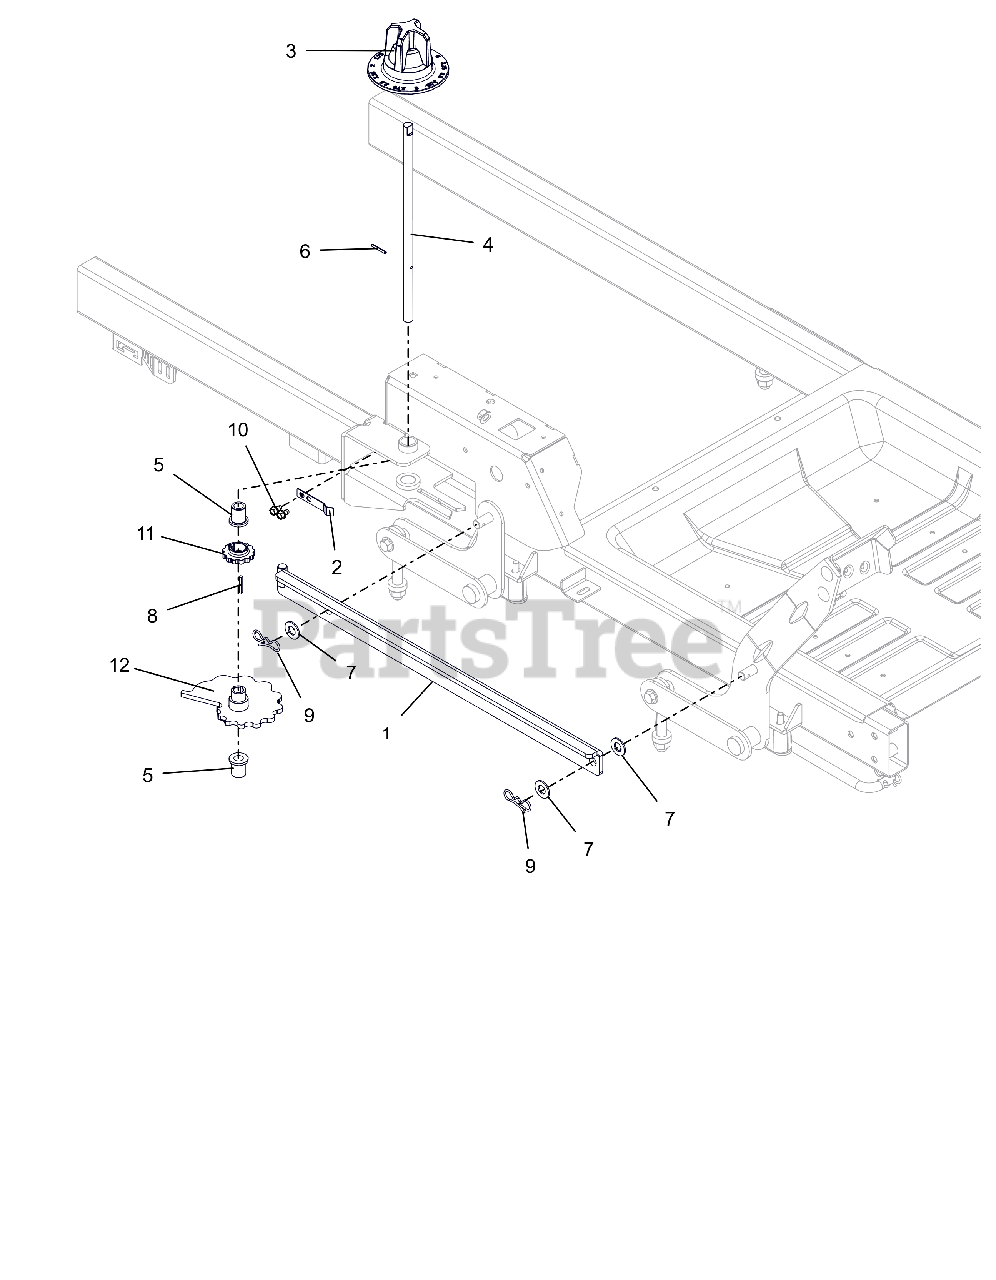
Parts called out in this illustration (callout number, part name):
1	WLDMT, HOC LINK
2	ARM, HOC DETENT
3	KNOB, HOC DIAL
4	SHAFT, HOC CAM IKON
5	BSHG-FLG, .503X.750X.875X1.00
6	PIN-ROLL .125X1.00
7	WSHR-FL-NYL .518X1.000X.080
8	KEY, 1/8 X 1/8 X 1.0
9	PIN,BOW TIE LOCKING .091X1.875
10	SCR,TAP .25-20X.375 HWH TR ZCC
11	GEAR, HOC INDEX
12	WLDMT, HOC CAM
